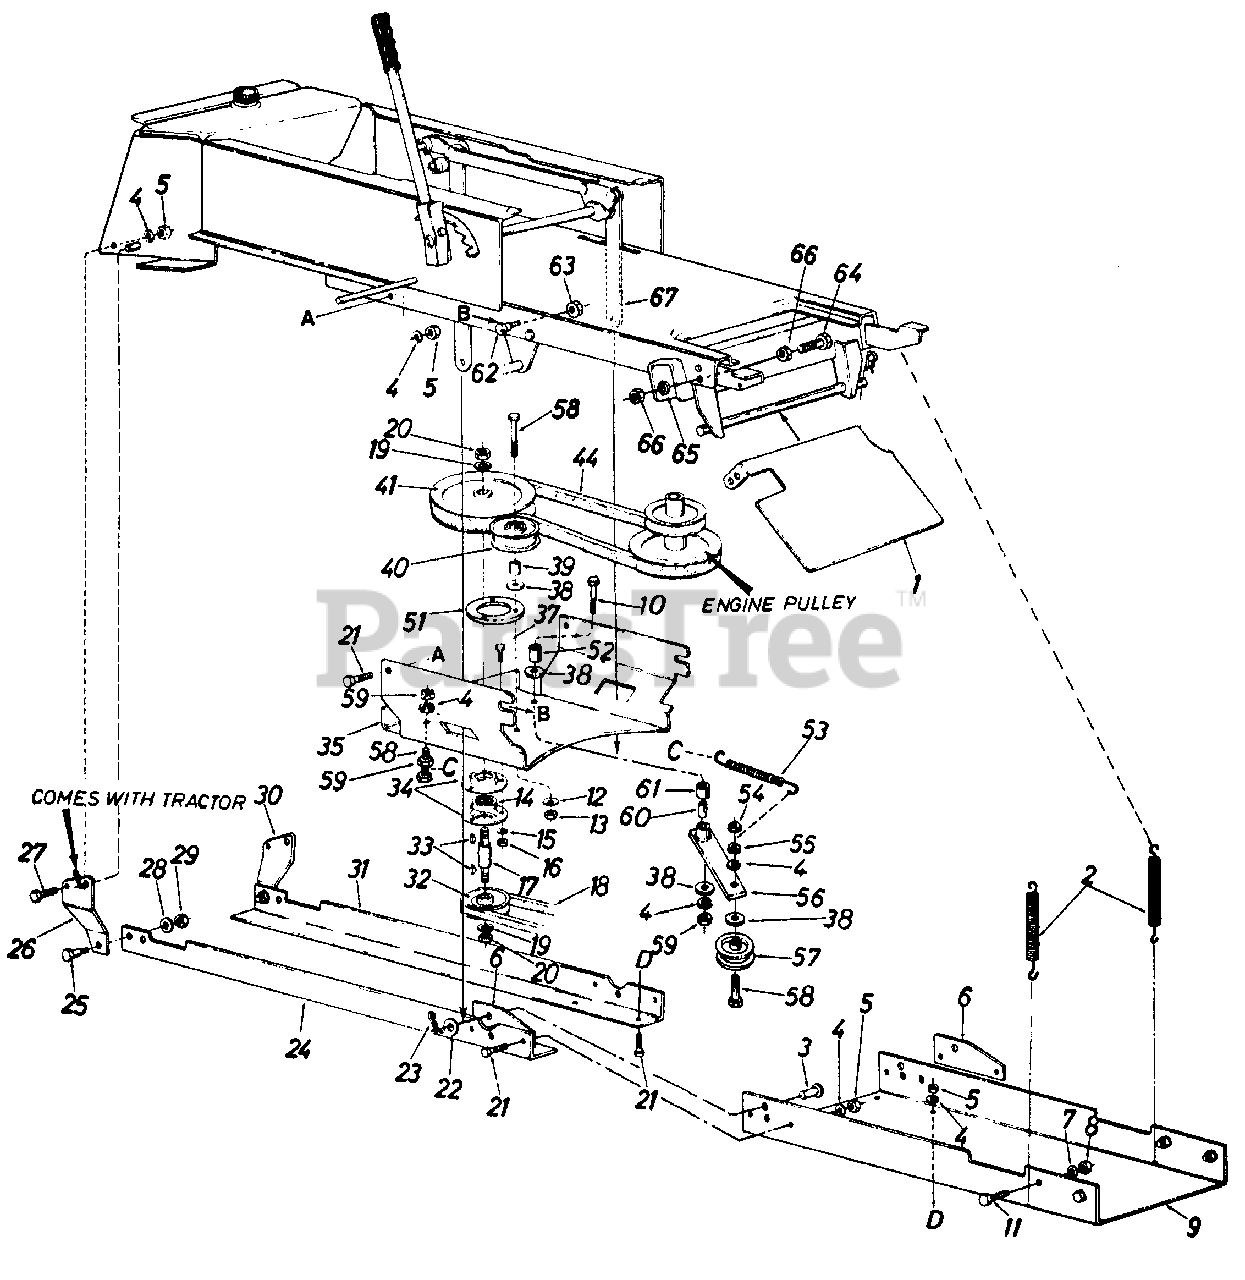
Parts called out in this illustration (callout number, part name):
1	Guide Bracket
2	Helper Spring
3	Clevis Pin
4	L.-Wash. 3/8" I.D.*
5	Hex L.-Nut 3/8-24 Thd.
6	Attaching Plate
7	L.-Wash. 1/2" I.D.*
8	Hex L.-Nut 1/2-20 Thd.
9	Front Support Channel
10	Hex Bolt 3/8-16 x 3.75" 4.
11	Hex Bolt 1/2-20 x 1.25" Lg.*
12	L-Wash. 3/8" I.D.
13	Hex Jam Nut 3/8-16 Thd.
14	Ball Bearing
15	L.-Wash. 5/16" I.D.*
16	Hex nut 5/16-18 Thd.*
17	Spindle
19	L.-Wash. 5/8" I.D.*
20	Hex Jam Nut 5/8-11 Thd.
21	Hex Bolt 3/8-24 x 1.00" 4.*
22	Flat Washer
23	Internal Cotter Pin
26	Rear Hanger Brkt.-R.H.
27	Hex Bolt 3/8-24 x 1.0" Lg.*
28	Fl.-Wash. 44" I.D. x 1.38" O.D. x .130
29	Hex L.-Nut 7/16-24 Thd.
30	Rear Hanger Brkt.-L.H.
31	Rear Support Angle-L.H.
32	Lower Drive Pulley 5/8 x 5.56
33	#6 Hi-Pro Key 3/16 x 5/8' Dia.
34	Bearing Housing
35	Supporting Bracket
37	Hex Sems Bolt 5/16-18 x 1.00" Lg.
38	Fl.-Wash. .38" I.D. x 1.00" O.D. x .135
39	Spacer .38" I.D. x .62" O.D.
40	Fl.-ldler Pulley
41	Upper Drive Pulley
44	VBelt
53	Extension Spring .54" O.D. x 4.75" Lg.
54	Hex Cent. L.-Nut 3/8-16 Thd.
55	Hex Jam Nut 3/8-16 Thd.
56	Idler Arm Ass'y.
57	Idler PUllev
58	Hex Bolt 3/8-16 x 2.25" Lg.
59	Hex Jam Nut 3/8-16 Thd.
60	Spacer.377" I.D. x .60" O.D. x .830" Lg.
61	Spacer .380" I.D. x .630" O.D. x 565" Lg.
62	Shoulder Bolt .498 Dia. x .340
63	Hex Cent. L.-Nut 3/8-16 Thd.
64	Hex Bolt 1/4-28 x 1.50" Lg.
65	L.-Wash. 1/4" I.D.
66	Hex Nut 1/4-28 Thd.
67	Lift Link
